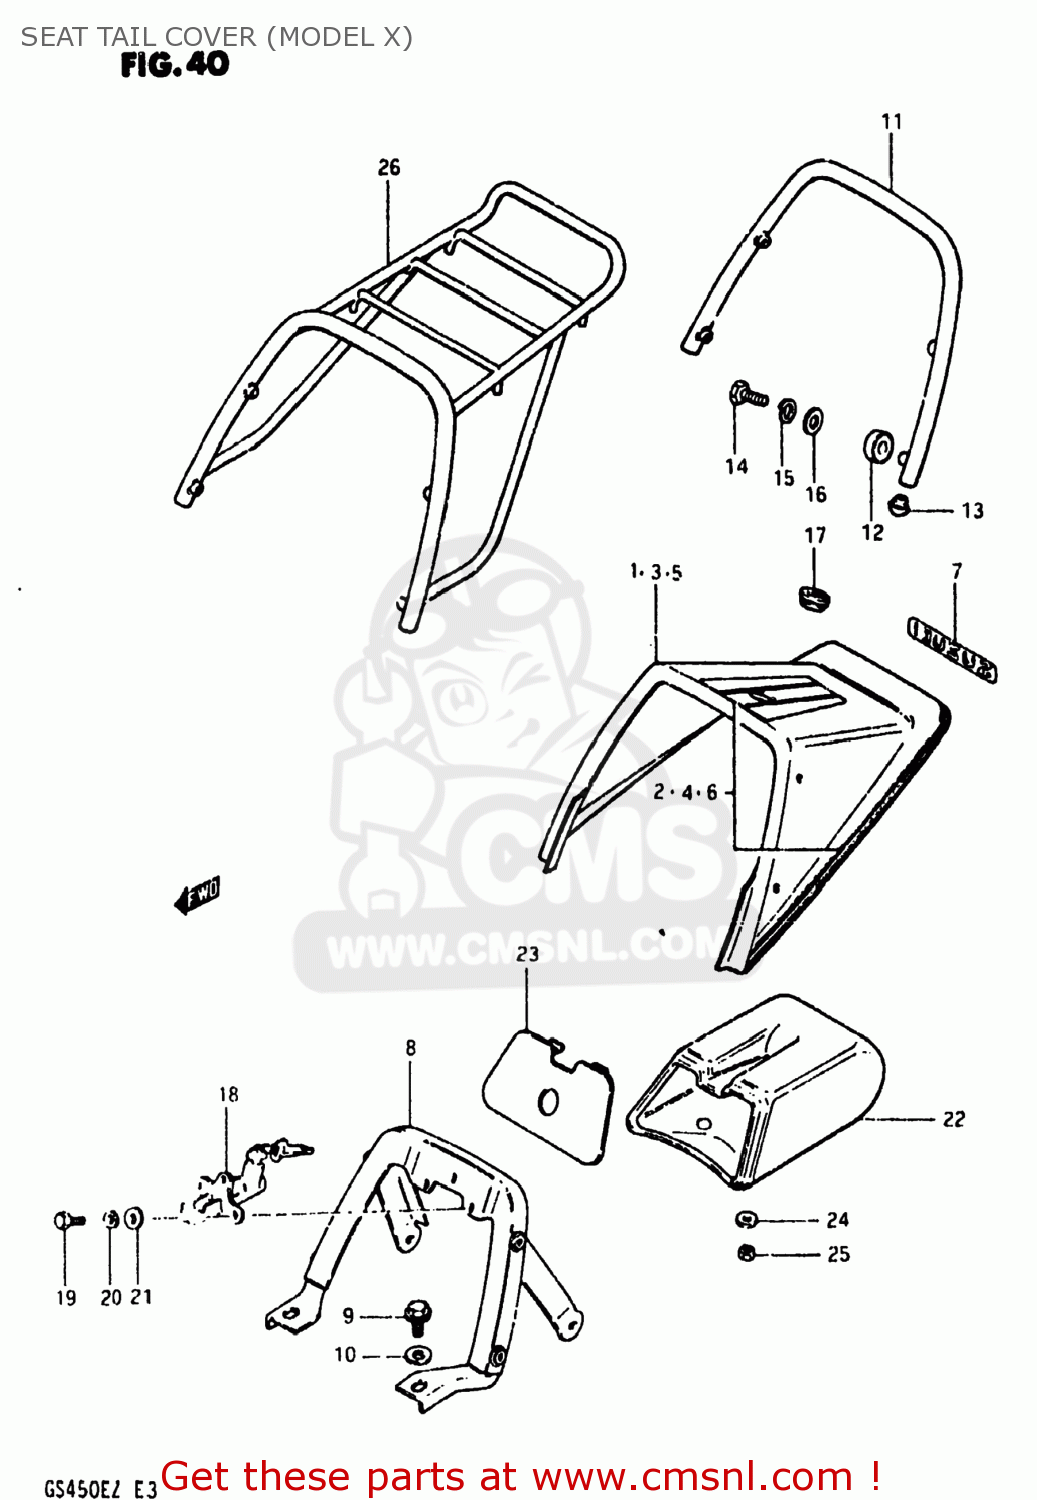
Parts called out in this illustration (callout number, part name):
1	COVER,SEAT TAIL
2	TAPE SET,SEAT TAIL COVER
3	COVER,SEAT TAIL
4	TAPE SET,SEAT TAIL COVER
5	COVER,SEAT TAIL
6	TAPE SET,SEAT TAIL COVER
7	EMBLEM (GOLD/BLACK)
8	BRACKET, SEAT TAIL COVER
9	BOLT
10	WASHER (8.7X22X2)
11	HANDLE,PILLION RIDER
12	CUSHION
13	END,SHEET HANDLE
14	BOLT (8X30)
15	LOCK WASHER
16	WASHER
17	GROMMET,SEAT LOCK HOLE
18	LOCK SET
19	BOLT
20	LOCK WASHER
21	WASHER
22	BOX, SEAT TAIL
23	LID,SEAT TAIL BOX
24	WASHER
25	NUT 6MM
26	CARRIER
